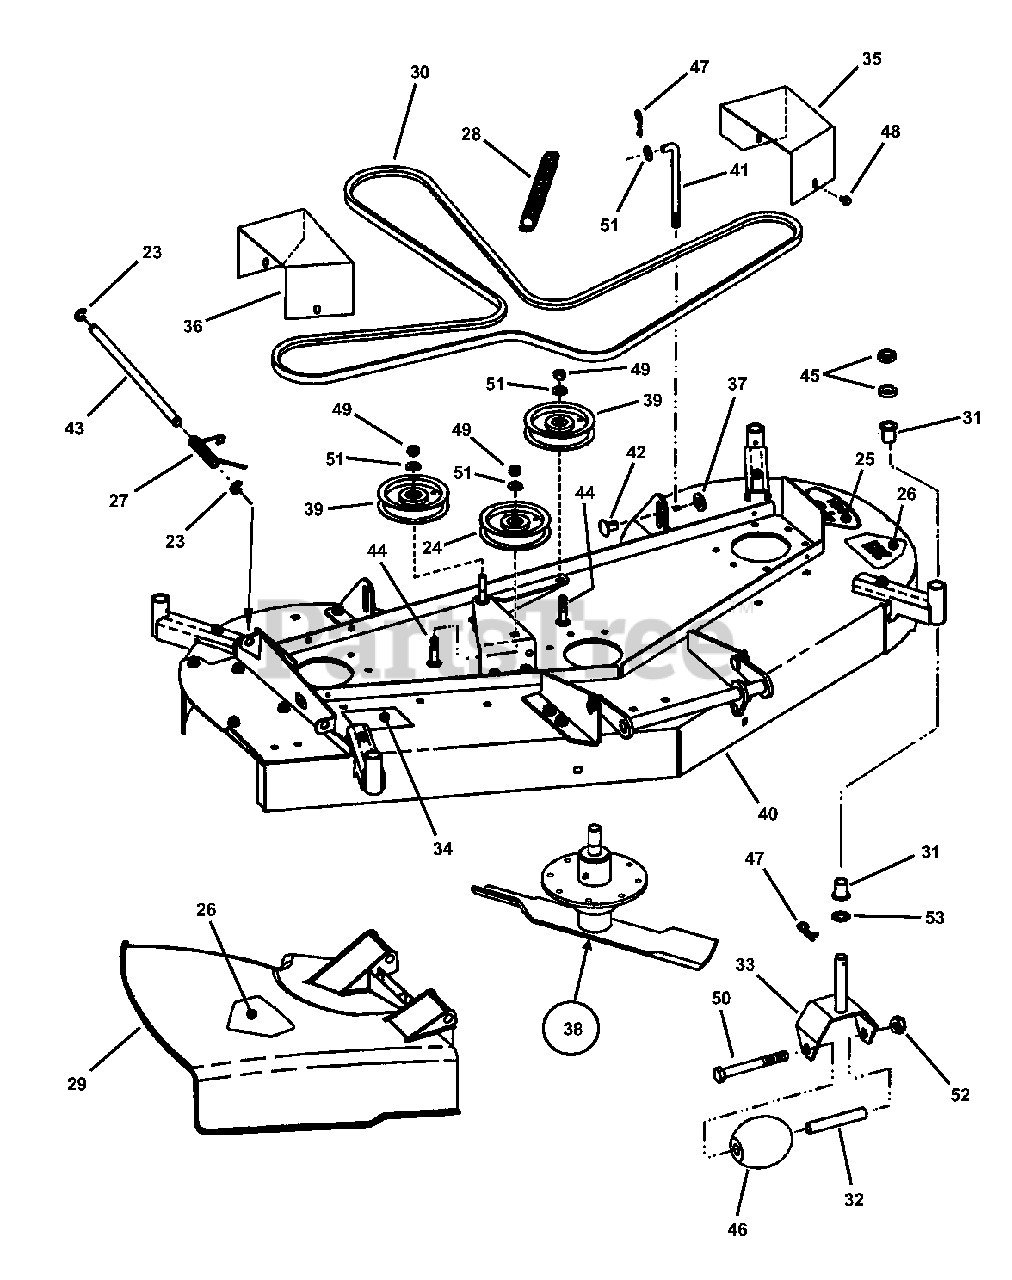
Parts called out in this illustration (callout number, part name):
23	RING, External Retaining
24	IDLER, 4.12" Flat
25	DECAL, 48" Deck
26	DECAL, CPSC
27	SPRING, Chute
28	SPRING, Idler Primary
29	CHUTE, Side Discharge
30	V-BELT, HA Section,
31	BUSHING, Flange 1/2 x 3/4" O. D. Plastic
32	SLEEVE, Caster Wheel
33	WELDMENT, Bracket/Shaft Caster
34	DECAL, Chute/Deflector
35	COVER, Belt L.H.
36	COVER, Belt R.H.
37	WASHER, 1/2" Flat
38	ASSEMBLY, 48" Spindle
39	IDLER, 3-1/4" Flat
40	ASSEMBLY, 48" Painted Mower Deck
41	LINK, Leveling
42	SUPPORT, Swivel
43	HINGE PIN, Chute
44	BOLT, 3/8-16 x 1-3/4" Short Neck Carriage, Grade 5
45	SPACER, Blade
46	ROLLER, Low Density Polyethylene
47	HAIR PIN, 3/32 x 1-1/2"
48	SCREW, 1/4-20 x 3/8" Hex Washer Self-Tap
49	NUT, 3/8-16 Hex Center Lock, Grade 5 or B
50	SCREW, 1/2-20 x 4-1/2" Hex Head Cap, Grade 5
51	WASHER, 3/8" Flat
52	NUT, 1/2-20 Hex Center Lock,
53	WASHER, .64 I.D. Flat
